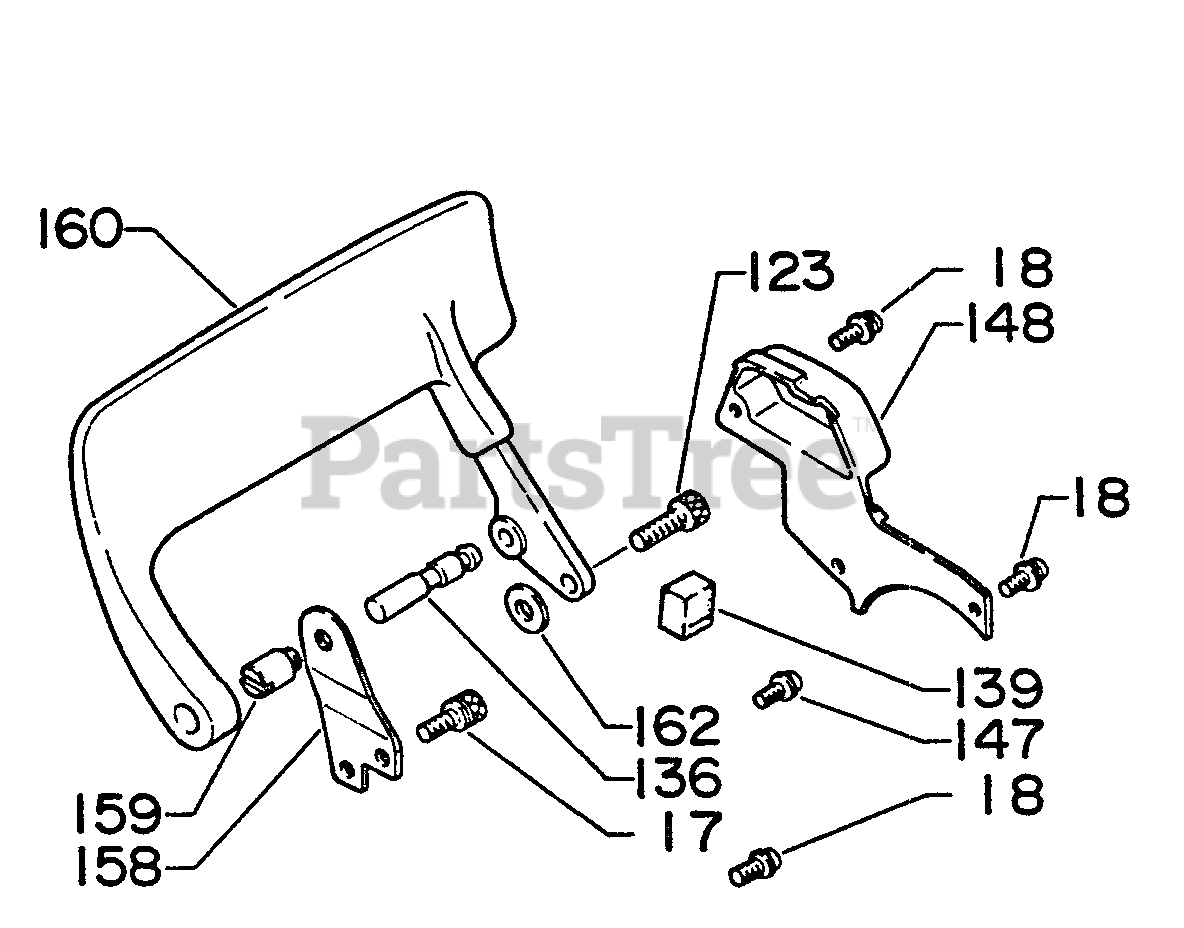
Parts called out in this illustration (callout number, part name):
17	SCREW - 5×15
18	SCREW - 4×12
123	BOLT 6×20
135	COVER, BRAKE
139	SEAL, DUST
147	SCREW 5×14
160	GUARD, HAND
161	BOLT 6×20
162	WASHER 6.5×18×1.6
